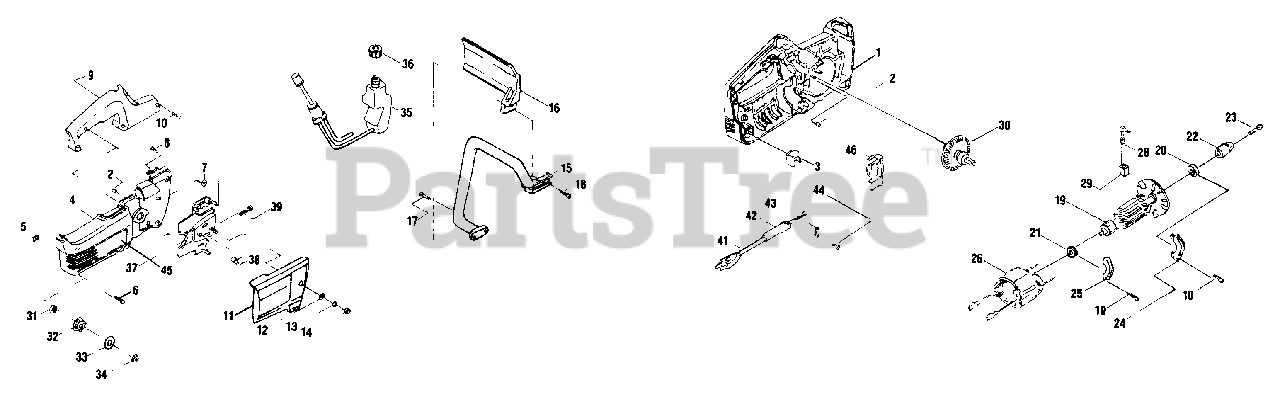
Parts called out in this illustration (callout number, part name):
1	CASE - LEFT
2	BUSHING
3	HOLDER (L)
4	CASE - RIGHT
5	HOLDER (R)
6	SCREW - TAPPING
7	PACKING
8	SCREW - 4X10 -- TAPPING
9	HANDLE - REAR
10	SCREW - TAPPING
11	BAR HOLDER ASSY
12	WASHER - 8
13	LOCKWASHER - 8
14	NUT - 8
15	HANDLE - FRONT
16	GUARD, HAND
17	SCREW -- TAPPING
18	SCREW
19	ARMATURE
20	BEARING, BALL - 6000
21	BEARING, BALL - 627ZZ
22	GEAR - PINION
23	SCREW - 4X25
24	CLAMP, FRONT
25	CLAMP - REAR
29	HOLDER, BRUSH
30	MAIN GEAR ASSY
32	SPROCKET
33	PLATE, SIDE
34	NUT
35	OILER TANK ASSY
36	CAP
37	BAR MOUNT ASSY
38	TENSIONER, CHAIN
39	SCREW, TENSIONER
41	POWER CORD
42	PROTECTOR, CORD
44	SCREW - TAPPING
45	NAME PLATE
46	SWITCH
